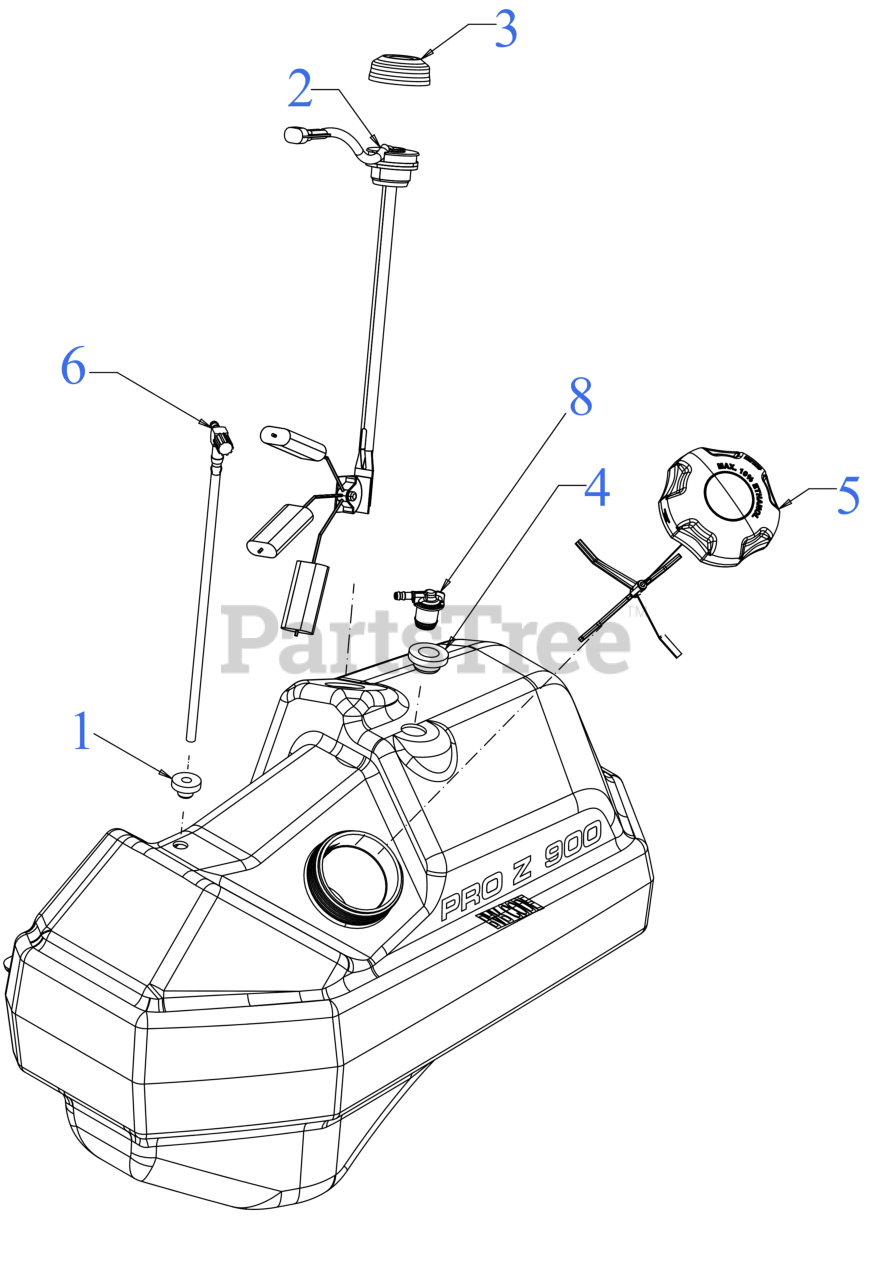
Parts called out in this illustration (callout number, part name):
1	GROMMET-FUEL TANK
2	FUEL LEVEL SENSOR
3	CASTER AXLE CAP
4	GROMMET .755 x .955 x .55
5	FUEL CAP - 3.50" ONE WAY VENT
6	FUEL PICKUP VALVE
8	FUEL VENT FITTING
